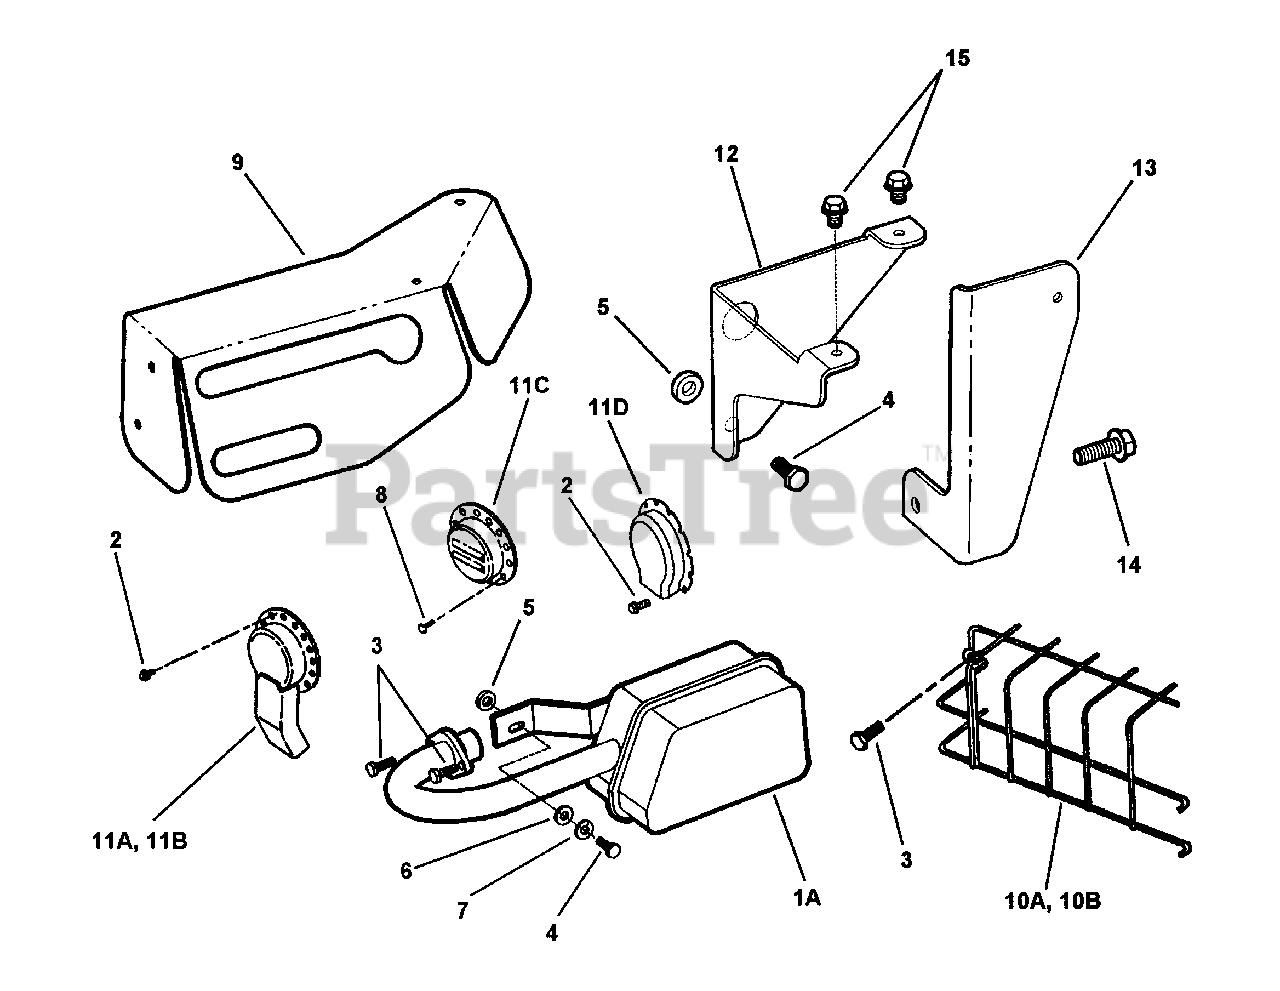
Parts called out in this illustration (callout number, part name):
1A	MUFFLER, 8HP Briggs
2	SCREW, #8-18 x 1/2" Self-Tap (28" w/Briggs)
3	SCREW, 1/4-20 x 3/4" Hex Head Cap, Grade 5
4	SCREW, 1/4-20 x 1" Hex Head Cap, Grade 5
5	SPACER
6	WASHER, 1/4" Flat
7	WASHER, 1/4" Split Lock
8	SCREW, #8-18 x 3/8" Hex Hd
9	SHIELD, Heat Euro RER
10A	GUARD, Muffler
10B	GUARD, Muffler
11A	DEFLECTOR, Heat
11B	DEFLECTOR, Heat
11C	DEFLECTOR, Heat
11D	DEFLECTOR, Heat
12	BRACKET, Heat Shield
13	BRACKET, Heat Shield
14	SCREW, 5/16-18 x 1" Hex Washer Self Tap
15	SCREW, 1/4-20 x 3/8" Hex Washer Self Tap
